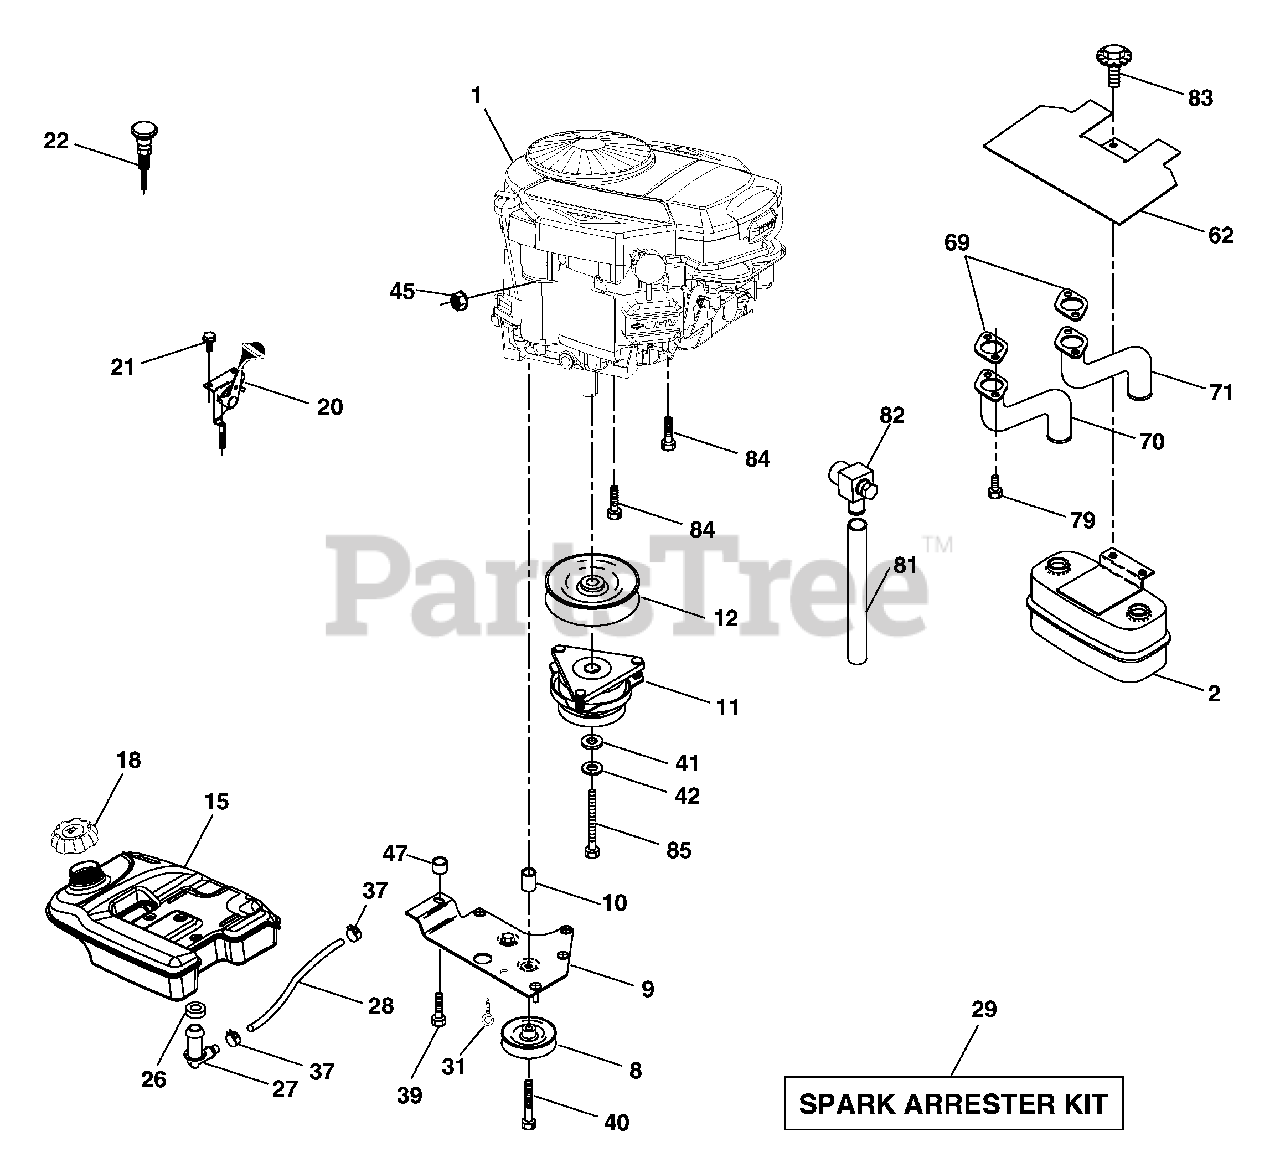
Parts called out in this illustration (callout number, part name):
2	Muffler Side
8	Pulley V-Idler
9	Keeper Asm. Belt Engine VGT
10	Bushing
11	Clutch Electric
12	Pulley Engine VGT Elect Clutch
15	Tank Fuel Rear 5.0
18	Cap Asm. Fuel
20	Control Throttle
21	Screw 10 x 3/4 Single Lead Hex
22	Control Choke
26	Bushing
27	Stem Tank Fuel
29	Spark Arrester Kit
31	Clip
37	Clamp Hose
39	Screw TT 3/8-16 x 2-1/4 unc
40	Screw TT 3/8-16 x 4 unc
41	Washer 1-1/2 OD x 15/32 ID x .250
42	Washer Lock 7/16
45	Nut Keps Hex 1/4-20 unc
47	Spacer
62	Shield Heat Muffler CV-Intek
69	Gasket
70	Tube Exhaust LH
71	Tube Exhaust RH
79	Screw Socket Head 5/16-18 x 1
81	Tube Drain Oil
82	Valve Oil Drain
83	Bolt 5/16-18 Unc x 1-3/4 W/Sems
84	Screw Thdrol 3/8-16 x 1-1/2
85	Bolt Hex 7/16-20 x 3.75 Gr. 5
86	Nut Hex Flange Toplock M8-1.25
